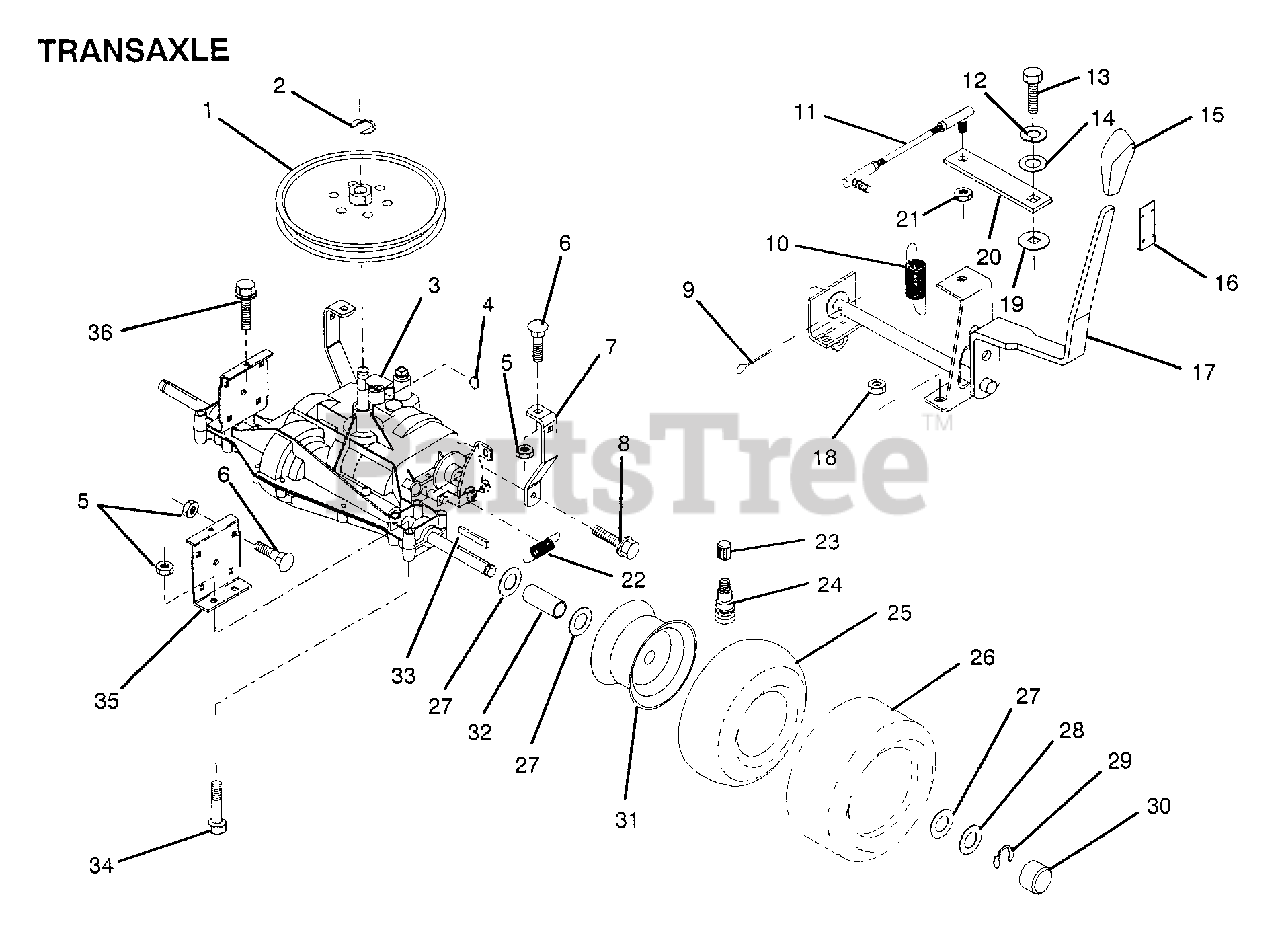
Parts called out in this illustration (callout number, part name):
1	PULLEY
6	BOLT
7	"STRAP,TORQUE"
8	SCREW LT
9	PIN COTTER 1/8
10	EXT SPRING
11	"LINK,SHIFT"
12	LOCKWASHER
14	WASHER LT
15	"KNOB,SHT CONTROL"
16	KNOB RETAINER
17	SHIFT HANDLE ASSY
19	WASH-SHFT PLT LT
20	ARM SHIFT
21	NUT.LOCK.5/16-24
23	VALVE CAP
24	VALVE STEM LT
25	TUBE.16X6.5/7.5-8
26	TIRE.16X7.5-8
27	WASHER
28	WASHER
29	E-RING LT
30	HUB CAP
32	SPACER
33	SQUARE KEY
34	BOLT
35	"BRKT,TRANSAXLE"
36	SCREW
